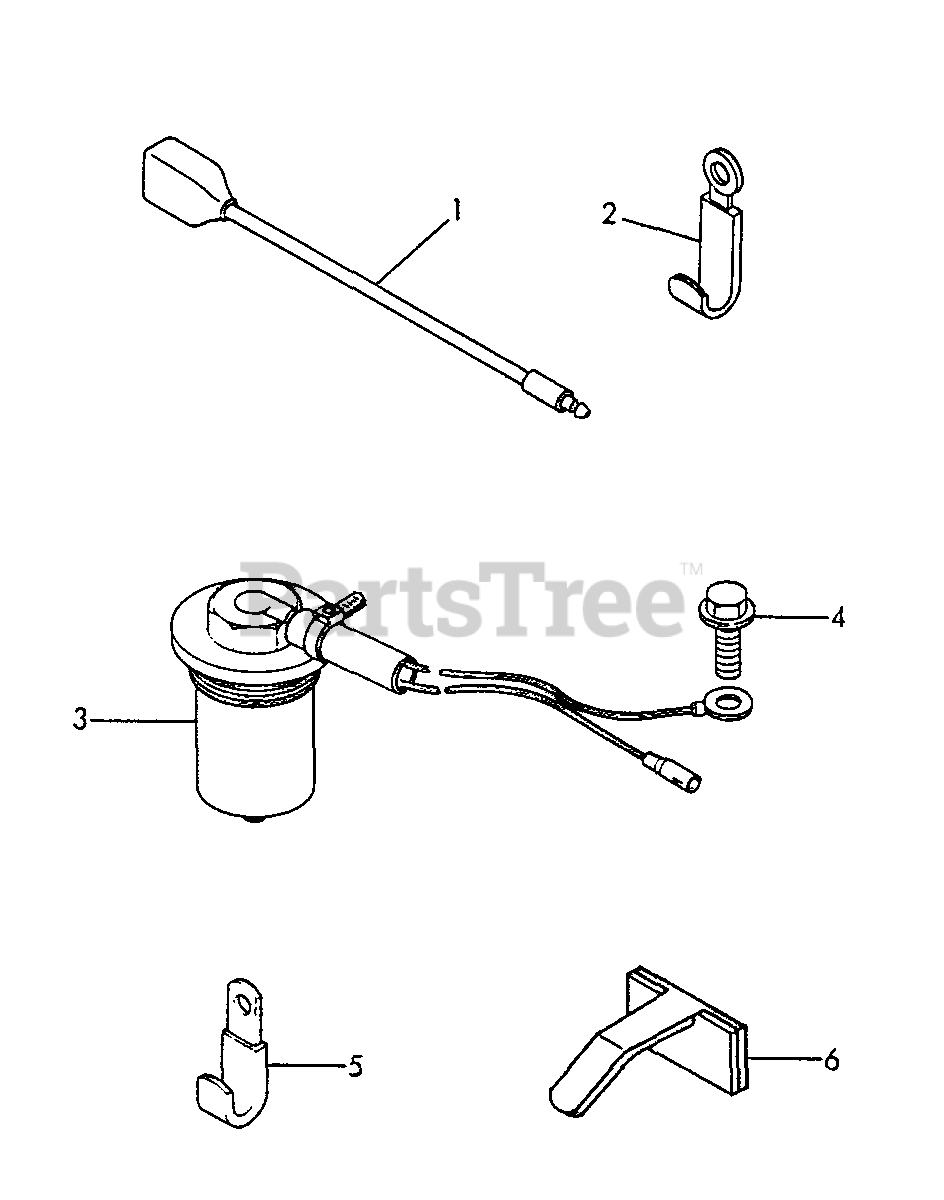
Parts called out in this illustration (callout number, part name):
2	CLAMP
3	SENSOR, OIL LEVEL
4	BOLT - 6×12
5	CLAMP
6	CLAMP
